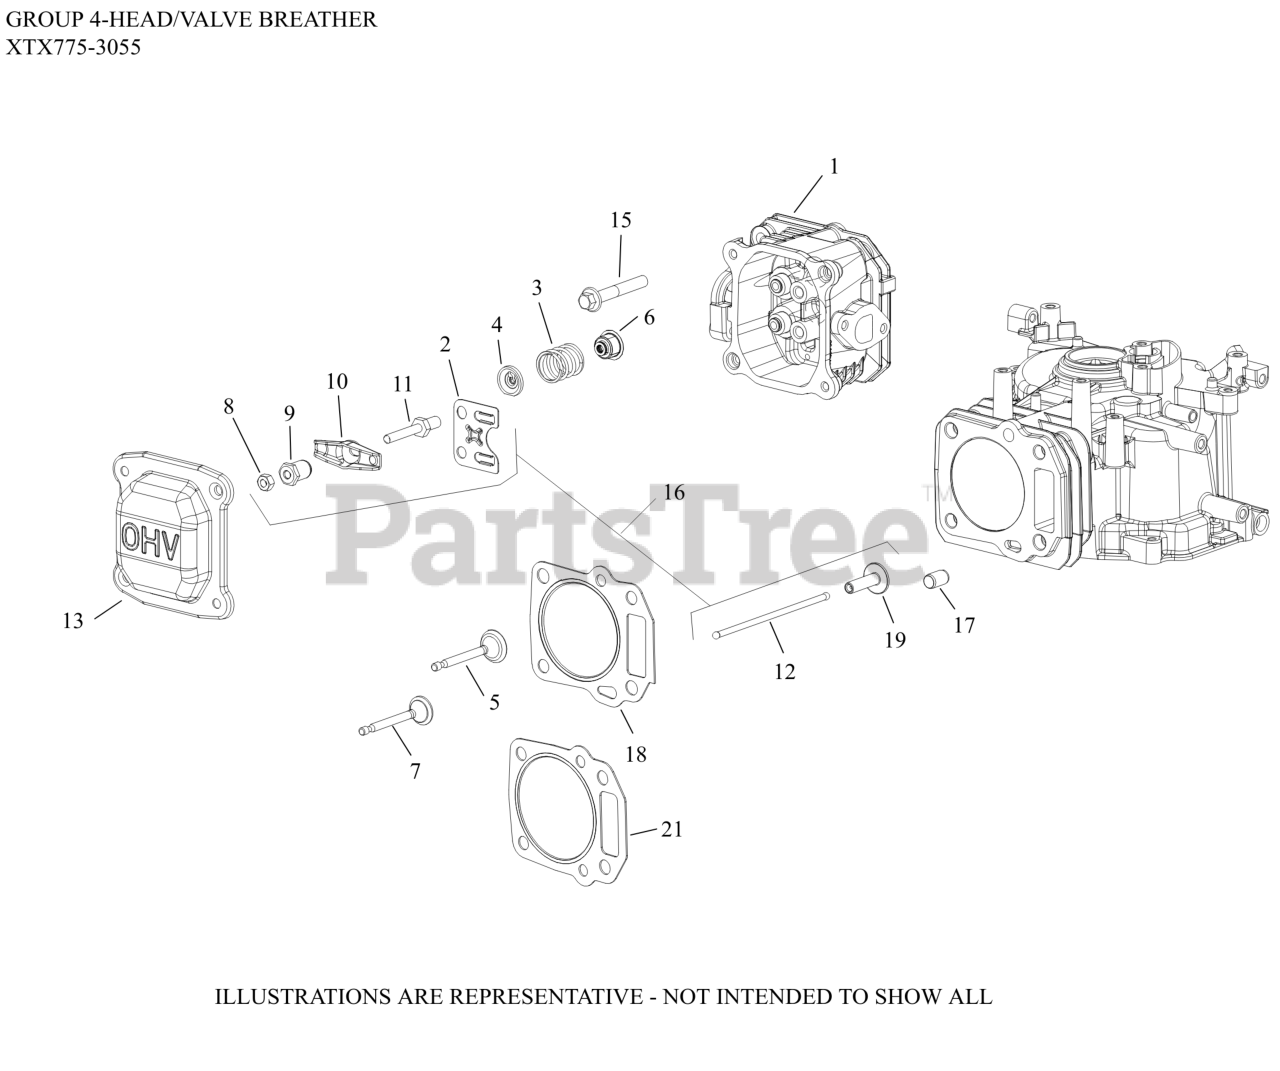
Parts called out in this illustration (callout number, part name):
1	HEAD, CYLINDER
2	PLATE, PUSHROD GUIDE
3	SPRING, VALVE
4	RETAINER, VALVE SPRING
5	VALVE, INTAKE
6	SEAL, VALVE STEM
7	VALVE, EXHAUST
8	NUT, HEX JAM
9	PIVOT, ROCKER ARM
10	ARM, ROCKER
11	STUD, ROCKER ARM
12	ROD, PUSH
13	COVER, VALVE
15	SCREW, HEX FLANGE M8
16	KIT, VALVE TRAIN
17	DOWEL, CYLINDER HEAD
18	KIT, HEAD GASKET-USE 14 841 34-S (XT)
19	LIFTER, VALVE
21	KIT, HEAD GASKET (CV173)
